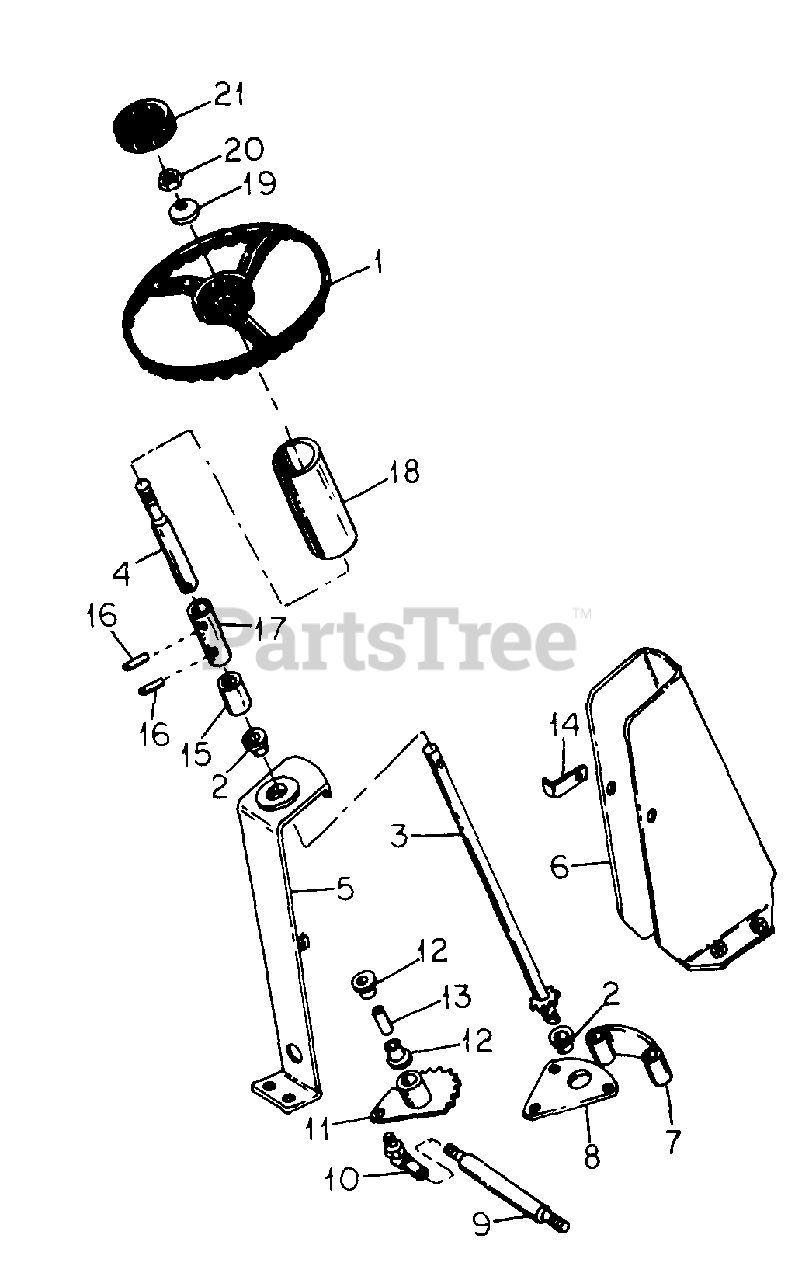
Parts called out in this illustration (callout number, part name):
1	WHEEL, STEERING
2	BEARING, STEERING SHAFT
3	SHAFT ASSY, LOWER STEERING
4	SHAFT, UPPER STEERING
5	SUPPORT ASSY, STEERING
6	SHROUD ASSY, STEERING SUPPORT
7	COVER, FRONT STEERING GEAR
8	COVER ASSY. STEERING GEAR
9	STUD, DRAG LINK ROD
10	JOINT, 3/8 C-Z TYPE G BALL
11	GEAR ASSY, STEERING DRAG LINK
12	BEARING, STEERING GEAR
13	BUSHING, STEERING GEAR DRAG LINK
15	SPACER, STEERING SHAFT
16	PIN, 1/4 X 1-3/8 MED PLN CLD SPR
17	BUSHING, SHAFT SLEEVE
18	SPACER, STEERING TUBE
19	WASHER, BELLEVILLE
20	NUT, 5/16 CAD P/T LOCK TYPE 5
21	CAP, STEERING WHEEL
